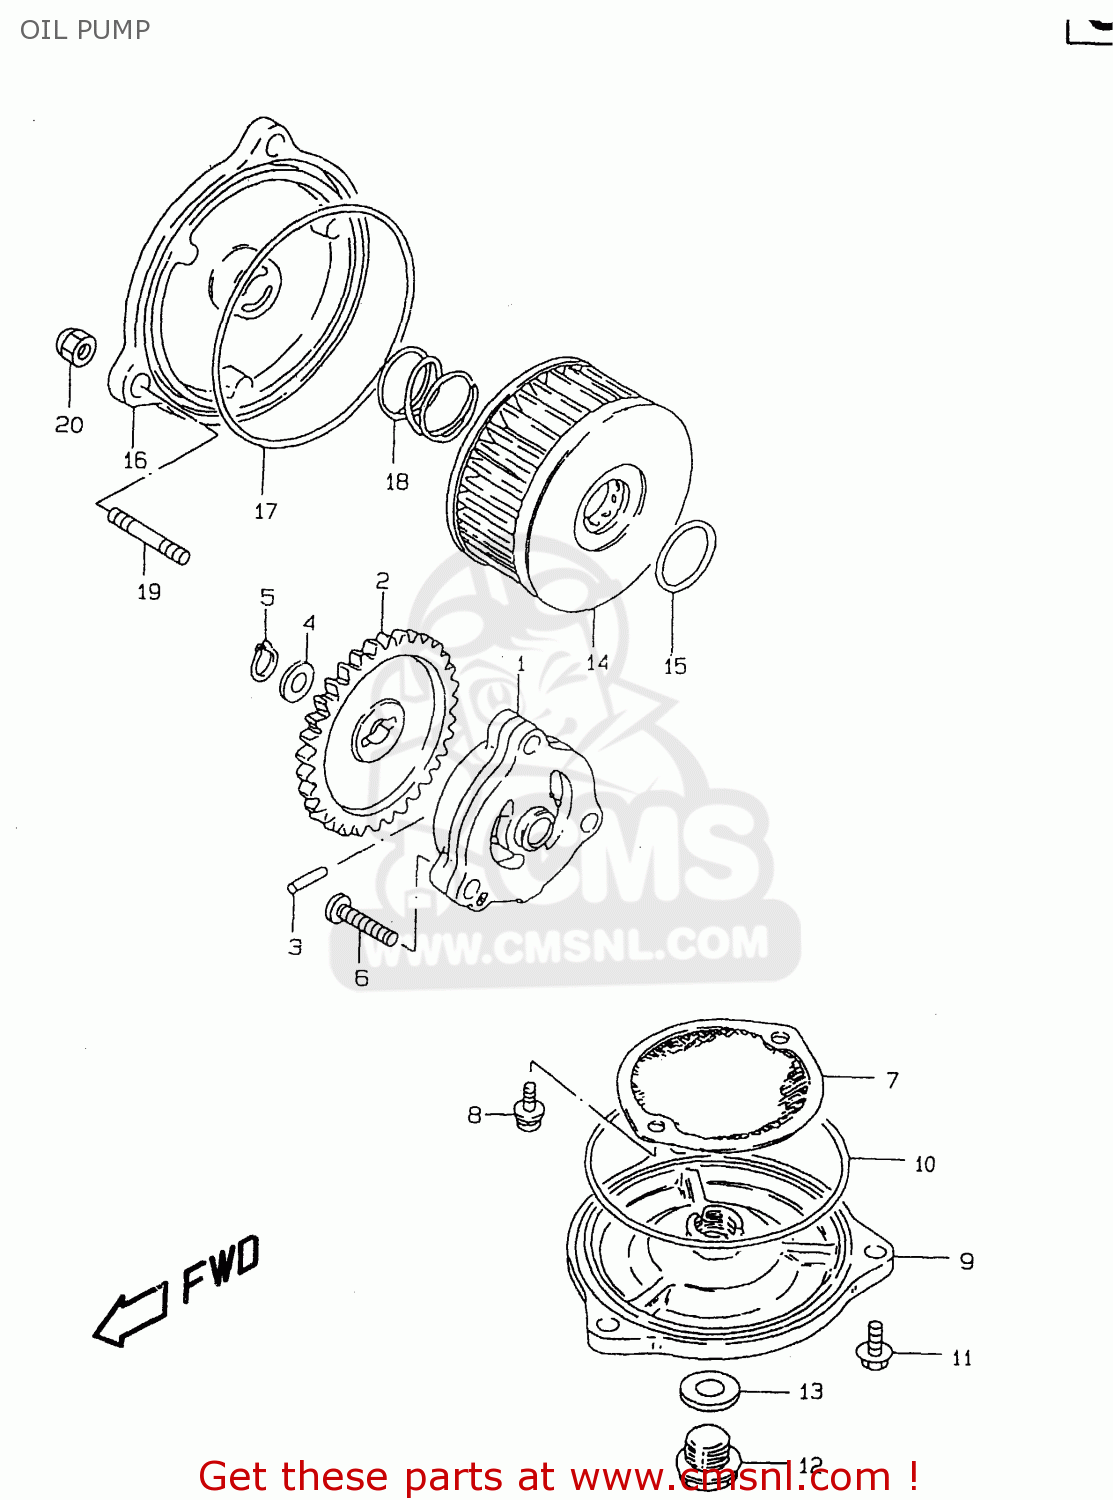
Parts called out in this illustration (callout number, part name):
1	PUMP ASSY,ENGINE OIL
2	GEAR,OIL PUMP DRIVEN(NT:33)
3	PIN(4X15.8)
4	SHIM(10X18X0.5)
5	CIRCLIP,10MM
6	SCREW
7	STRAINER,ENGINE OIL
8	SCREW
9	CAP,OIL STRAINER
10	O RING(D:2.4,ID:85)
11	SCREW
12	PLUG(14X12)
13	GASKET(13.8X18.8X4.8) (NAS)
14	FILTER ASSY,ENGINE OIL
15	O RING(D:2.4,ID:15.8)
16	CAP,OIL FILTER
17	O RING(D:2.4,ID:73)
18	SPRING
19	STUD 6X12
20	NUT
